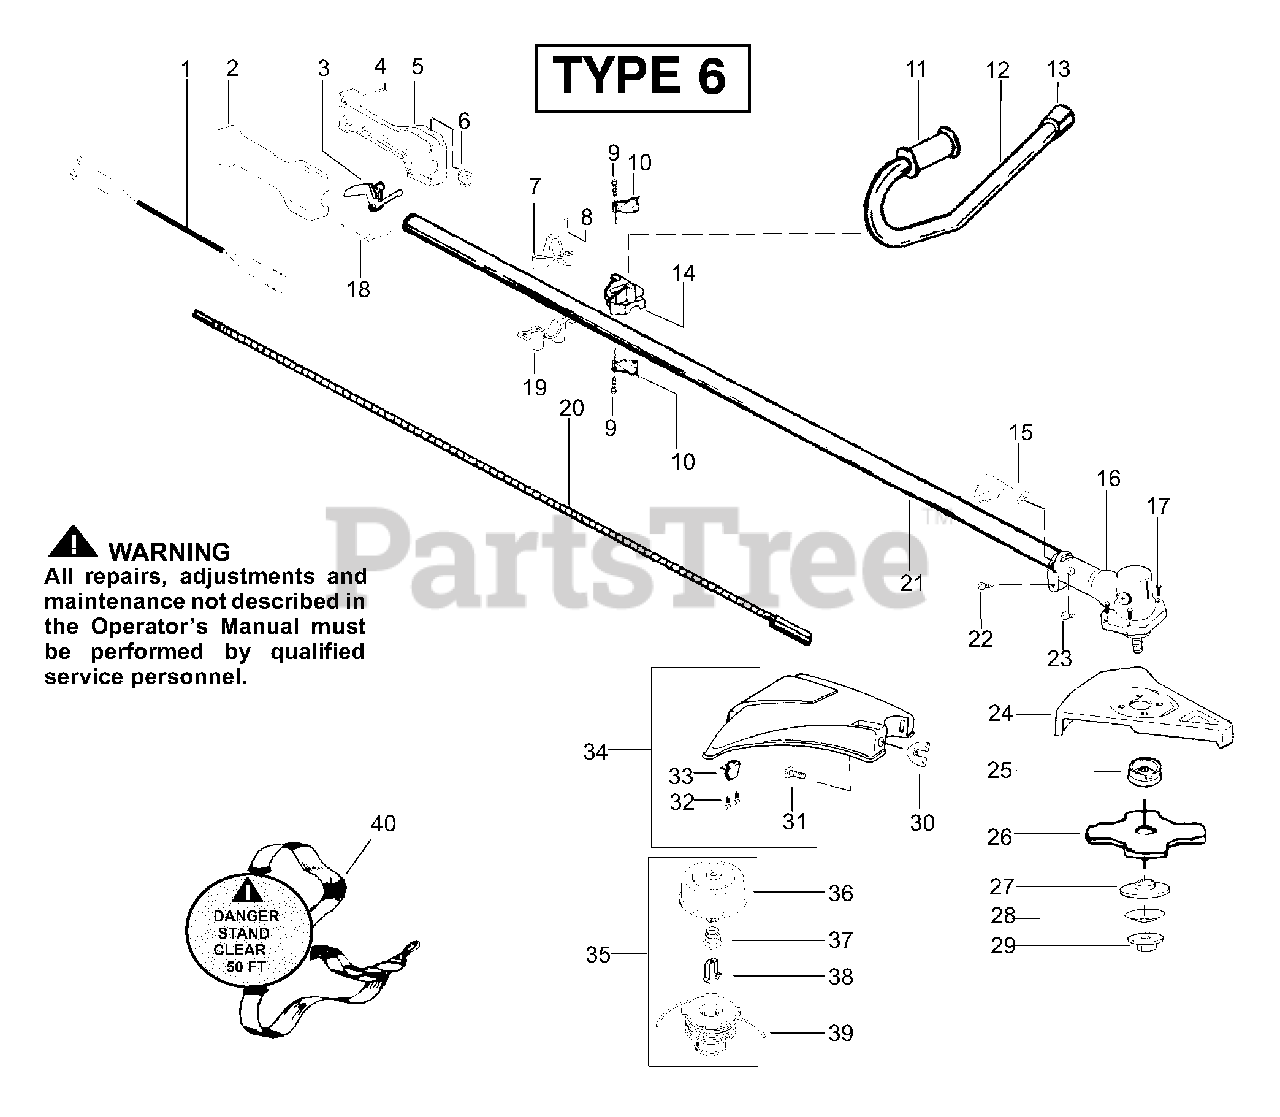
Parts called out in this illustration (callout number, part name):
2	Assy-Leadwire
2	Hsg.-Throttle Right
3	Lever-Throttle
5	Hsg.-Throttle Left
6	Kit-On/Off Switch
7	Clamp-Upper
10	Bracket-Handlebar
11	Grip-Handlebar
12	Kit-Handlebar Assy. w/decal
13	End Cap-Handlebar
14	Clamp-Handlebar
15	Bracket-Shield
16	Kit-Gear Box Ass'y.
18	Spring-lever return
19	Clamp-Lower
20	Shaft-Flex
21	Kit-Drive Shaft Assy
24	Kit-Metal Shield
25	Dust Cup
26	Accy-4 Point Blade
28	Washer-Belleville
29	Nut-Flange
30	Wingnut
32	Screw
33	Line Limiter
34	Kit-Shield Ass'y.
35	Accy-Cutting Head
36	Assy-Hub
37	Spring-Return
38	Retainer-Spool
39	Accy-Spool w/Line
40	Assy-Shoulder Strap
